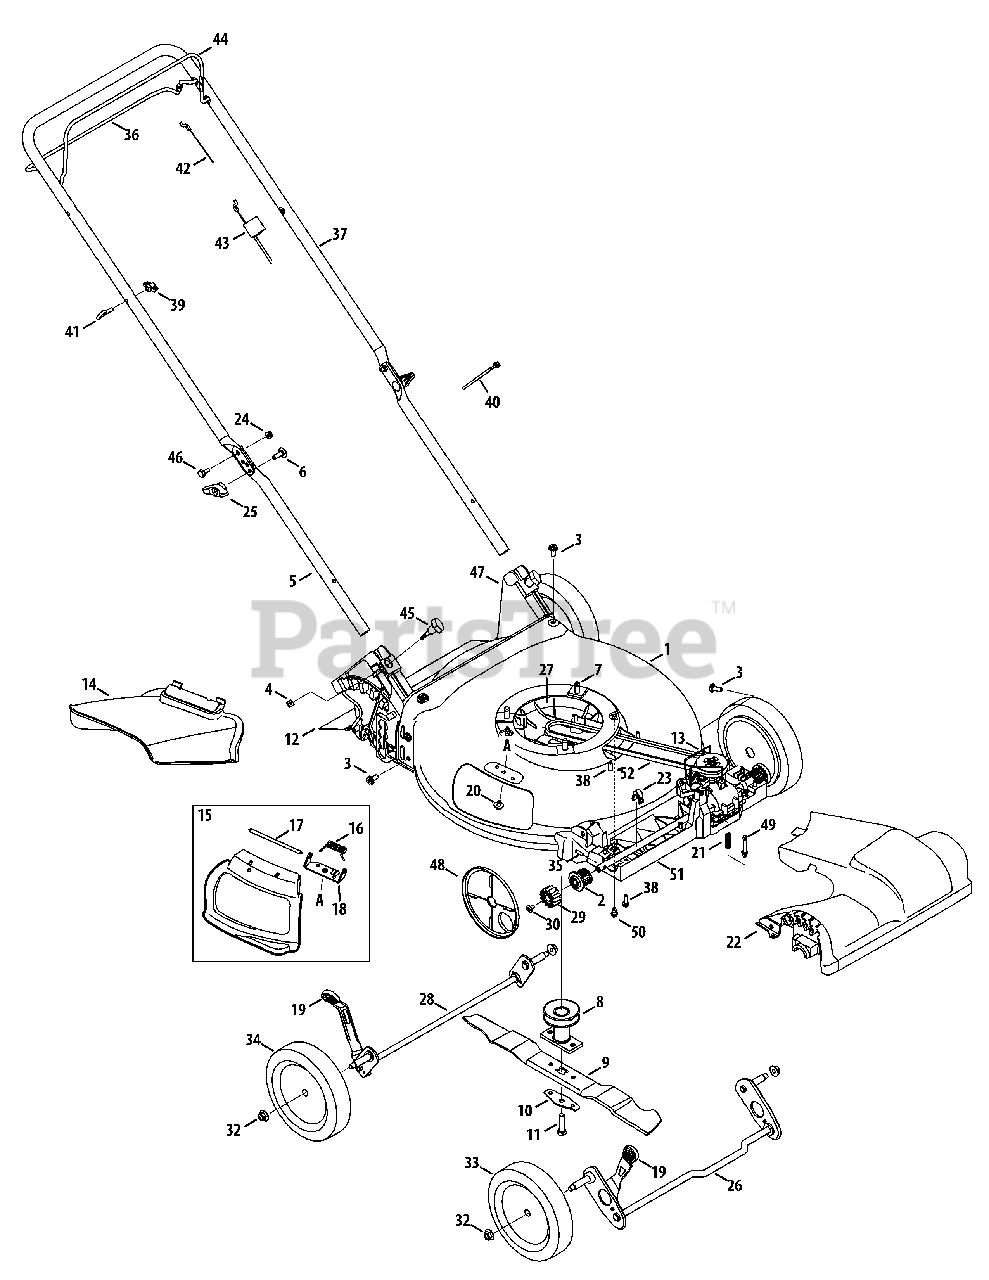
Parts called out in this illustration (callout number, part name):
1	Deck , 21"
2	Bearing Assembly
3	Screw, 5/16-14 x .750
4	Nut, Sq., 1/4-20
5	Lower Handle
6	Carriage Screw ,5/16-18
7	Screw, 3/8-16 x 1.00
8	Blade Adapter
9	Mulching Blade
10	Blade Bell Support
11	Screw, 3/8-24 x 1.50
12	Trailing Shield
13	Transmission Wire
14	Side Discharge Chute
15	Mulch Plug (Incl. 16-18)
16	Torsion Spring
17	Hinge Pin
18	Chute Deflector Bracket
19	Adjustment Lever Knob
20	Screw, 1/4-20 x .500
21	Compression Spring
22	Front Cover
23	Front Axle Clip
24	Nut, Flange Lock, 1/4-20
25	Wing Knob
26	Front Axle Assembly
27	Engine Baffle
28	Rear Axle Assembly
29	Spur Gear, 14T - RH
29	Spur Gear, 14T - LH
30	Screw, 1/4-20 x .390
31	Transmission Assembly
32	Flange Lock Nut, 3/8-16
33	Front Wheel
34	Rear Wheel
35	Dowel Pin
36	Drive Control
37	Upper Handle
38	Screw, 1/4-15 x .750
40	Cable Tie
41	Rope Guide
42	Control Cable
43	Drive Cable
44	Blade Control
45	Wing Nut
46	Sldr. Screw, .375 x .126 x 1/4-20
47	Rear Baffle
48	Wheel Dust Cover
49	Spring Body
50	Screw., Shldr., 1/4-20 x .50
51	Lower Tray
